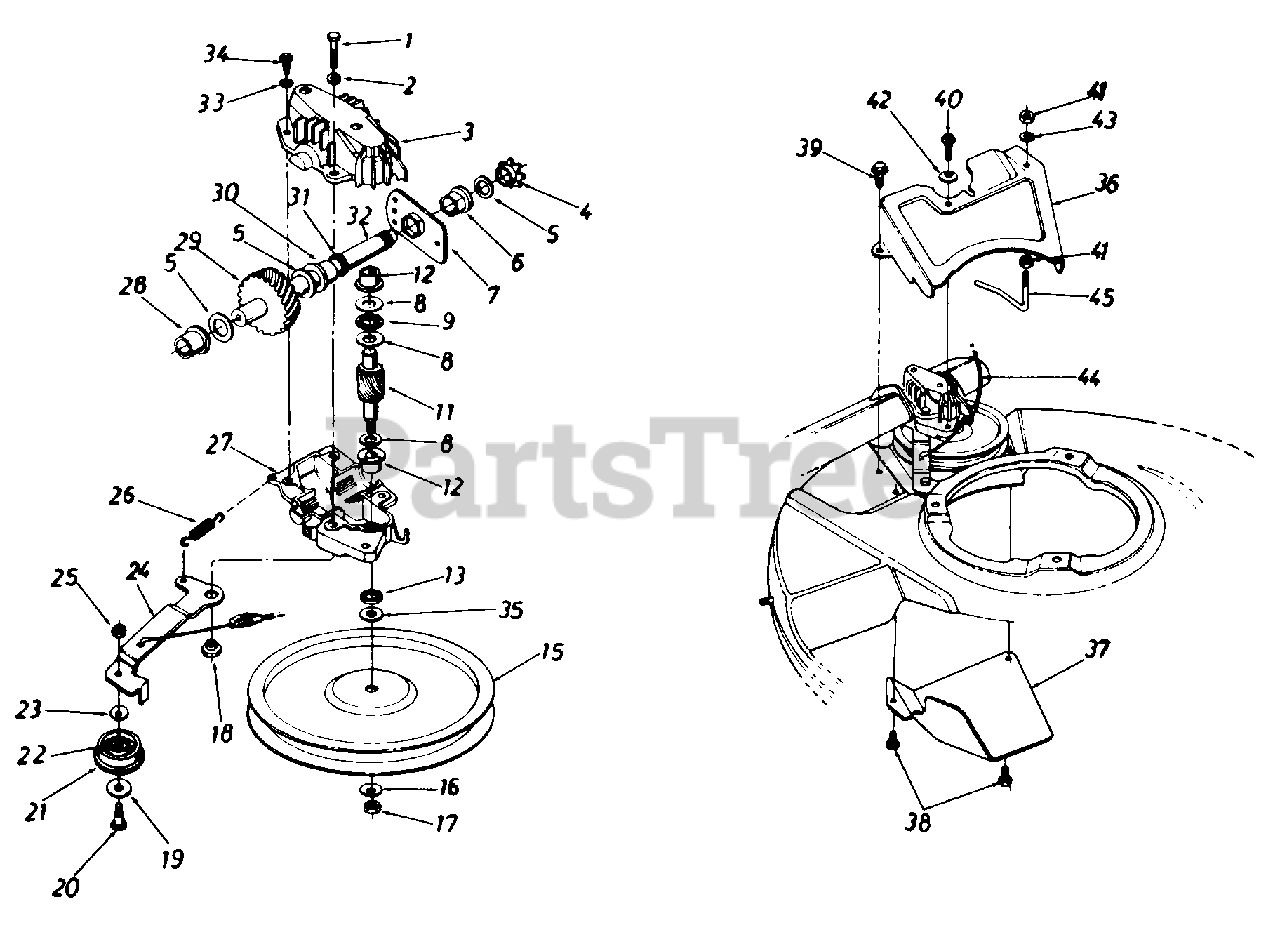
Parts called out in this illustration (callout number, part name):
1	Hex Bolt 1/4-20 x 1.25" w/Patch
2	L-Wash. 1/4" I.D.
3	Upper Hsg. Half
4	#48 Sprocket 7 Tooth x 1/2 Pitch
5	Fl-Wash. 5/8" I.D. x .030
6	Hex Flange Brg. .631" I.D.
8	Thrust Wash. .382" I.D. x .70" 0 D
9	Thrust Bearing
11	11 Tooth Helical Gear
12	Flange Bearing
13	Oil Seal
15	Fl-Pulley 5.06" I.D.t
16	Bell-Wash. .265" I.D. x .75
17	Hex Nut 1/4-28 L.H. Thd.
18	Shld. Spacer .375" Dia. x .170
19	Fl-Wash. .390" I.D. x 1.O"
20	Shld. Bolt .375" Dia. x .40"
21	Fl-Idler Plastic 1.5" Dia.
22	Needle Brg. .375" x .31"
23	Bell-Wash. .265" I.D.
24	Idler Brk't. Ass'y.
25	Hex Patch L-Nut 1/4-28 Thd.
26	Extension Spring 1.12" Lg.
27	Lower Hsg. Half
28	Flange Bearing .566 Dia.
29	33 Tooth Helical Gear
30	Flange Bearing .629 Dia.
31	Oil Seal .625 Dia.
32	Gear Sprocket Shaft
33	L-Wash. #10 I.D.
34	Hex B-Tap Scr. #10 x .62"
35	Hex Washer .26" x .88"t
39	Hex AB-Tap Scr. 1/4 x .50" Lg.
40	Hex B-Tap Scr. 1/4 x .62" Lg.
41	Hex Nut 1/4-20 Thd.
42	Bell-Wash. .265" I.D. x 75"
43	L-Wash. 1/4" I.D.
44	S.P. Cable-48" Lg.
45	S.P. Belt Guard
